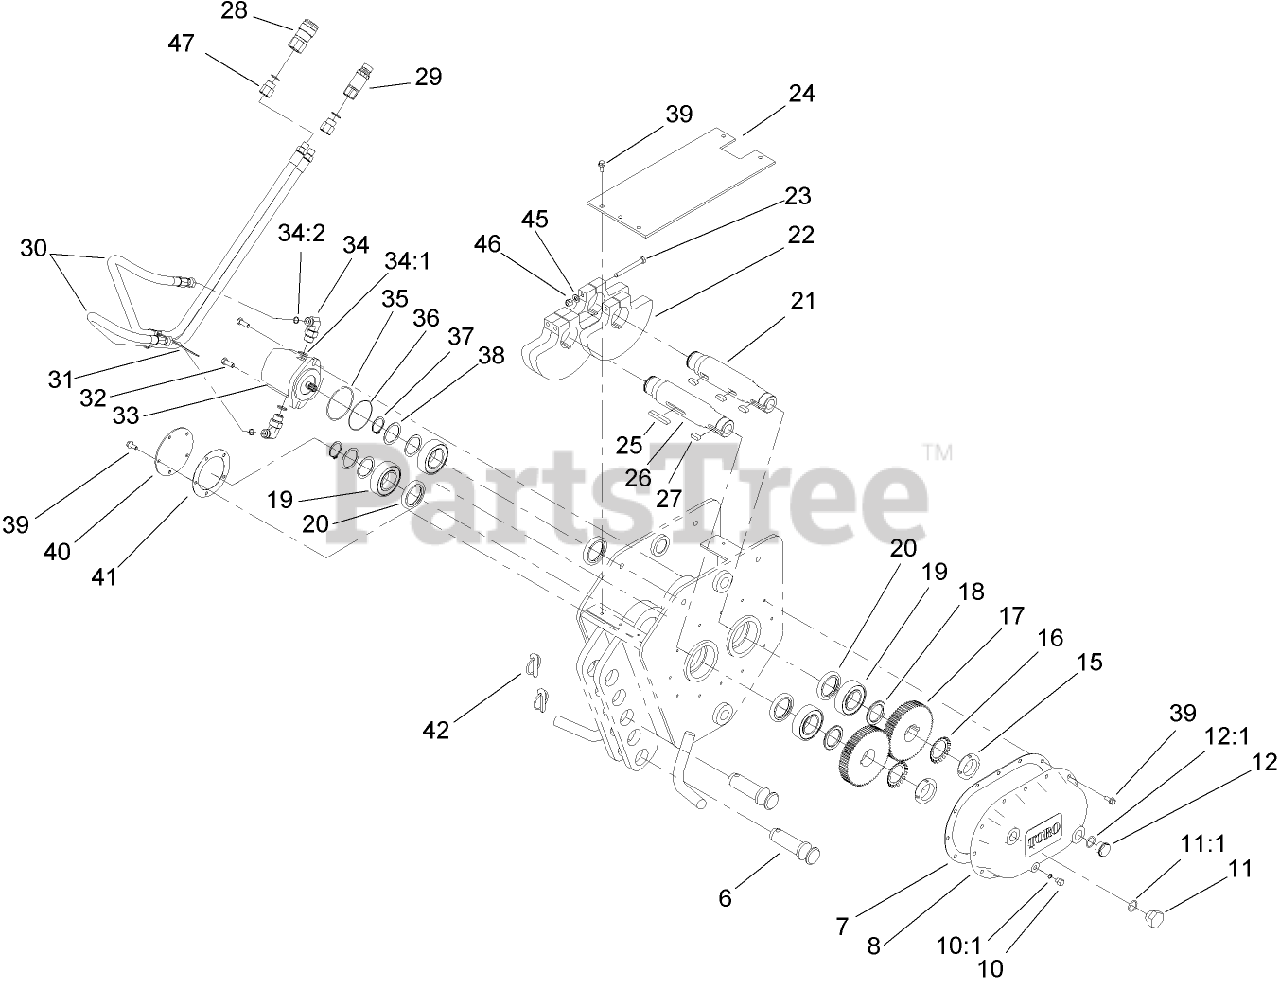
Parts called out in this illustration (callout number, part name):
6	PIN-BLADE
7	GASKET
10:1	O-RING
11	PLUG-HH
11:1	O-RING
12	GLASS-SIGHT
12:1	O-RING
16	RETAINER-NUT
18	SPACER
19	BEARING-ROLLER, SPHERICAL
20	SEAL-OIL
21	SHAFT-SPLINED
22	WEIGHT-COUNTER
23	SCREW-HH
24	PLATE-TOP
25	KEY-LONG
26	SHAFT
27	KEY-SHORT
28	COUPLER-FACE, FLUSH
29	NIPPLE-CONNECT, PRESSURE
30	HOSE-HYDRAULIC
31	TIE-CABLE
32	SCREW-HH
33	MOTOR-HYD
34	FITTING-ELBOW 90
34:1	O-RING
34:2	O-RING
35	RING-PILOT
36	O-RING
37	RING-RETAINING
38	WASHER-THRUST
39	SCREW-FLANGE
40	PLATE-COVER
41	GASKET
42	PIN-LYNCH
45	WASHER-FLAT
46	NUT-LOCK, NI
47	ADAPTER-HYD
